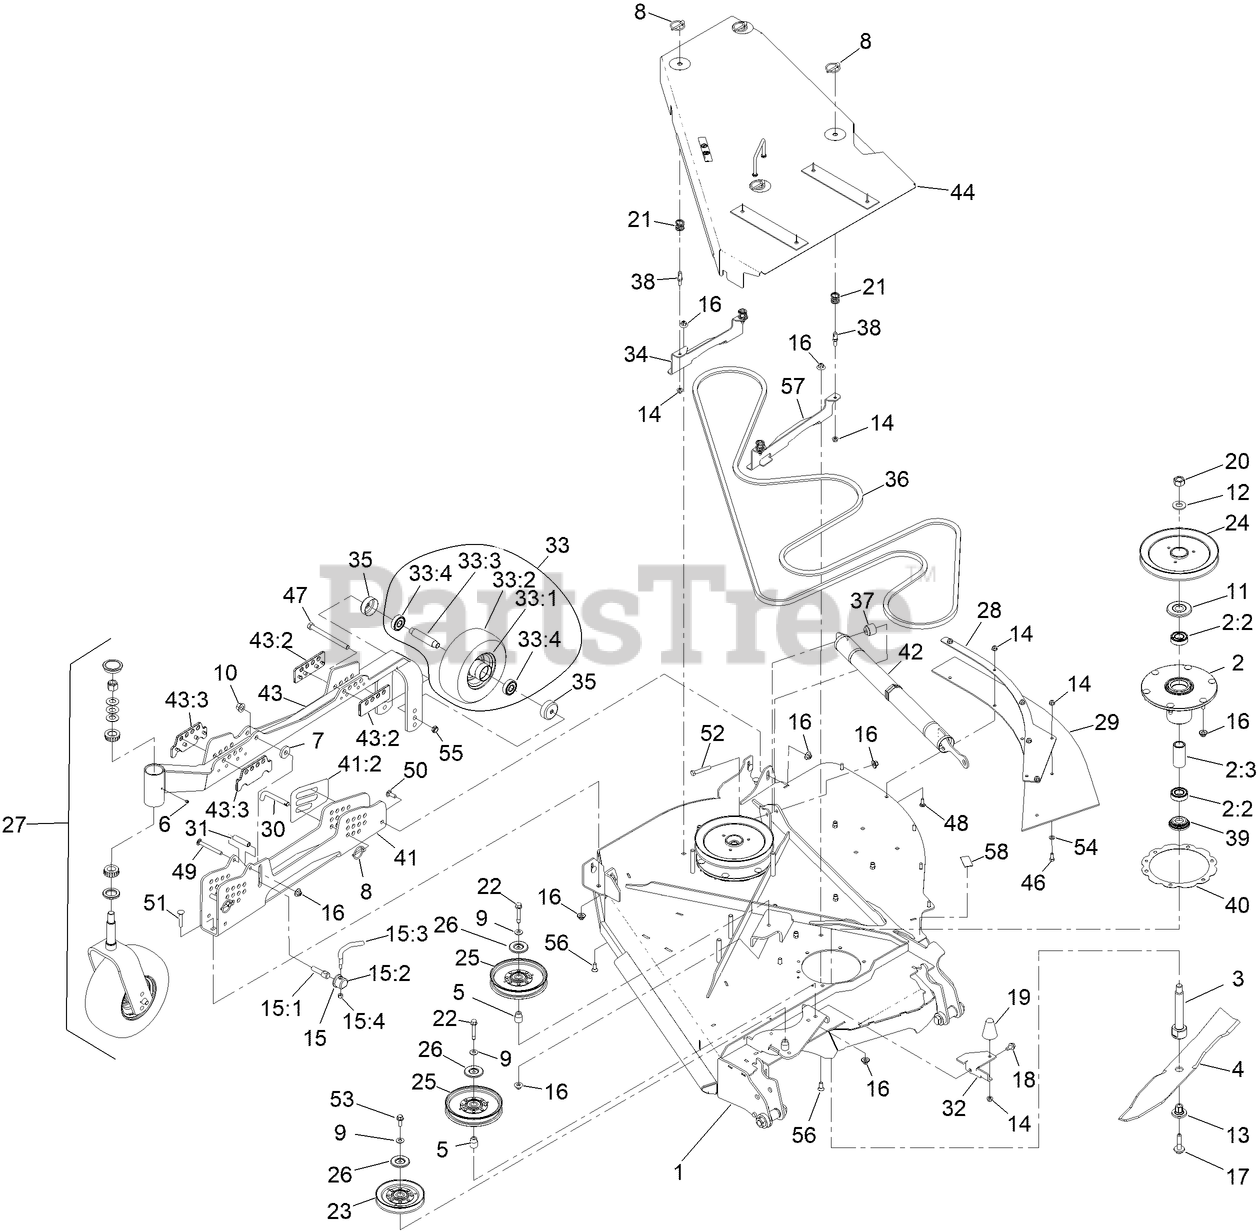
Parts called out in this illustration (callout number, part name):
1	ASM-DECK, RH WING [W/DECALS]
2	SPINDLE ASM
2:2	BEARING-BALL
2:3	SPACER-BEARING
3	SHAFT-SPINDLE
4	BLADE-24.50 MULCH
5	BUSHING-IDLER
7	WASHER
8	PIN-LYNCH
9	WASHER-BELLEVILLE
10	NUT-LOCK
11	GUARD-BEARING, TOP
12	WASHER
13	BUSHING-HEX
14	NUT-HF, NI
15	LEVER ASM
15:1	SCREW-LOCK
15:2	CAP-LOCK
15:4	NUT-LOCK, NI
16	NUT-FLANGE, NI
17	SCREW-SEMS
18	SCREW-HWH
19	BUMPER-RUBBER
20	NUT-HEX
21	SPRING
22	SCREW-HHF W/ PATCH
23	IDLER-V
24	SHEAVE-DRIVE, BLADE
25	IDLER-PULLEY
26	SHIELD-DUST
27	CASTER WHEEL ASM
28	SUPPORT-RH REAR GUARD
29	GUARD-RH WING REAR
30	PIN-HOC
31	SPACER
32	BRACKET-COVER RETAINER
33	WHEEL AND TIRE ASM
33:1	WHEEL
33:3	AXLE-CASTER
33:4	BEARING
34	BRACKET-SHIELD MOUNT, OUTER
35	GUARD, SEAL
36	BELT,V-5V-198.75
37	BUSHING-LIFT SPRING
38	PIN, SPRING
39	GUARD-BOTTOM
40	RING-SPACER, HOUSING
41	ASM-CHANNEL, HOC RH W/DECALS
41:2	DECAL-HEIGHT OF CUT, RH
42	ASM-WEIGHT-TRANSFER-SPRING
43	ASM-RH GAUGE WHEEL ARM
43:2	PLATE-GUIDE, REAR
43:3	PLATE-GUIDE, FRONT
44	ASM-BELT SHIELD RH
46	SCREW-HH
47	SCREW-HH
48	SCREW-CARR
49	SCREW-CARR
50	BOLT-CARR
51	SCREW-CARR
52	SCREW-HH
53	SCREW-HHF
54	WASHER-PLAIN
55	NUT-HEX
56	BOLT-CARR
57	BRACKET-SHIELD MOUNT, RIGHT LONG
58	PAD-RUBBER
